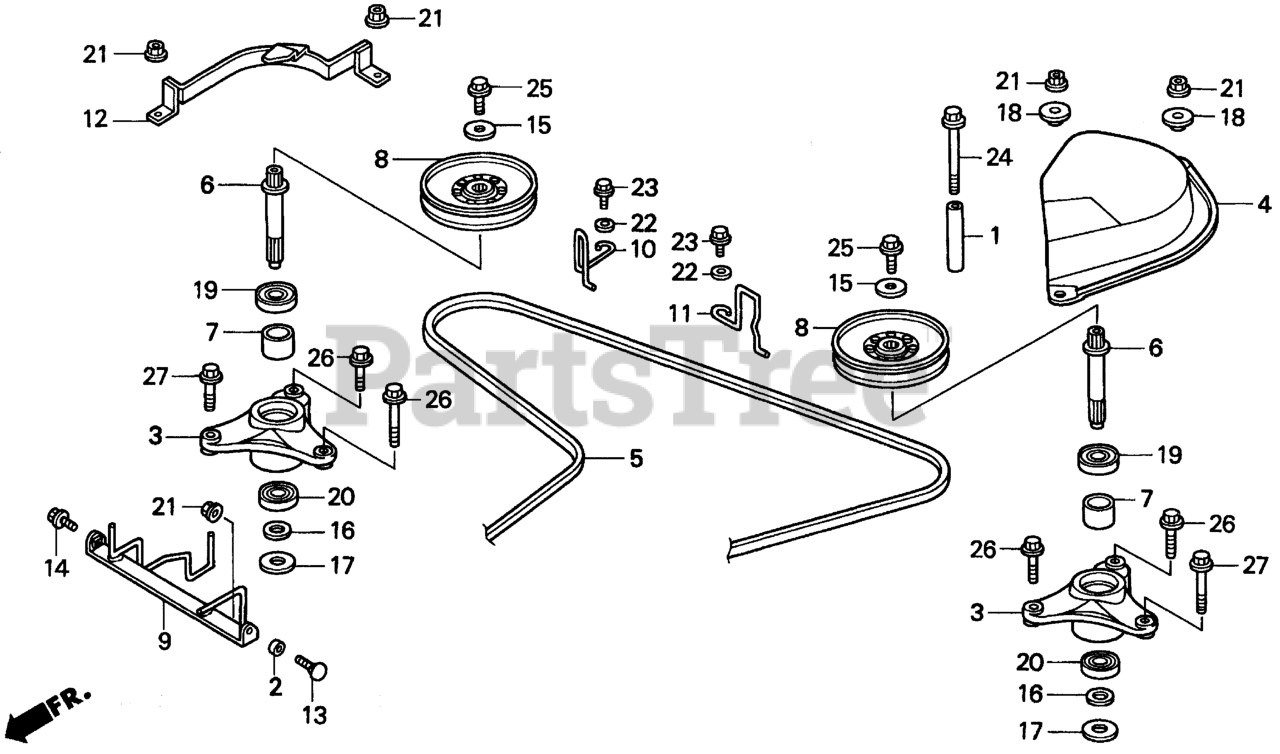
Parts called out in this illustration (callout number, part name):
1	SHAFT, FR. WHEEL PIPE
3	HOUSING, BEARING
4	COVER, L. BELT
5	V-BELT, BLADE (5L-88) (W600 SB-87) (BANDO)
6	SHAFT, BLADE
7	COLLAR, BLADE SHAFT
8	PULLEY, BLADE
10	STOPPER B, BELT
11	STOPPER C, BELT
12	STOPPER E, BELT
15	WASHER (10.5X27X4)
16	WASHER, THRUST (20MM)
17	WASHER, BLADE HOLDER
18	COLLAR, RR. FENDER SETTING
19	BEARING, RADIAL BALL (6204)
20	BEARING, RADIAL BALL
21	NUT, FLANGE (8MM)
22	WASHER, PLAIN (8MM)
23	BOLT, FLANGE (8X20)
24	BOLT, FLANGE (8X75)
25	BOLT, FLANGE (10X25)
26	BOLT, FLANGE (10X30)
27	BOLT, FLANGE (10X45)
